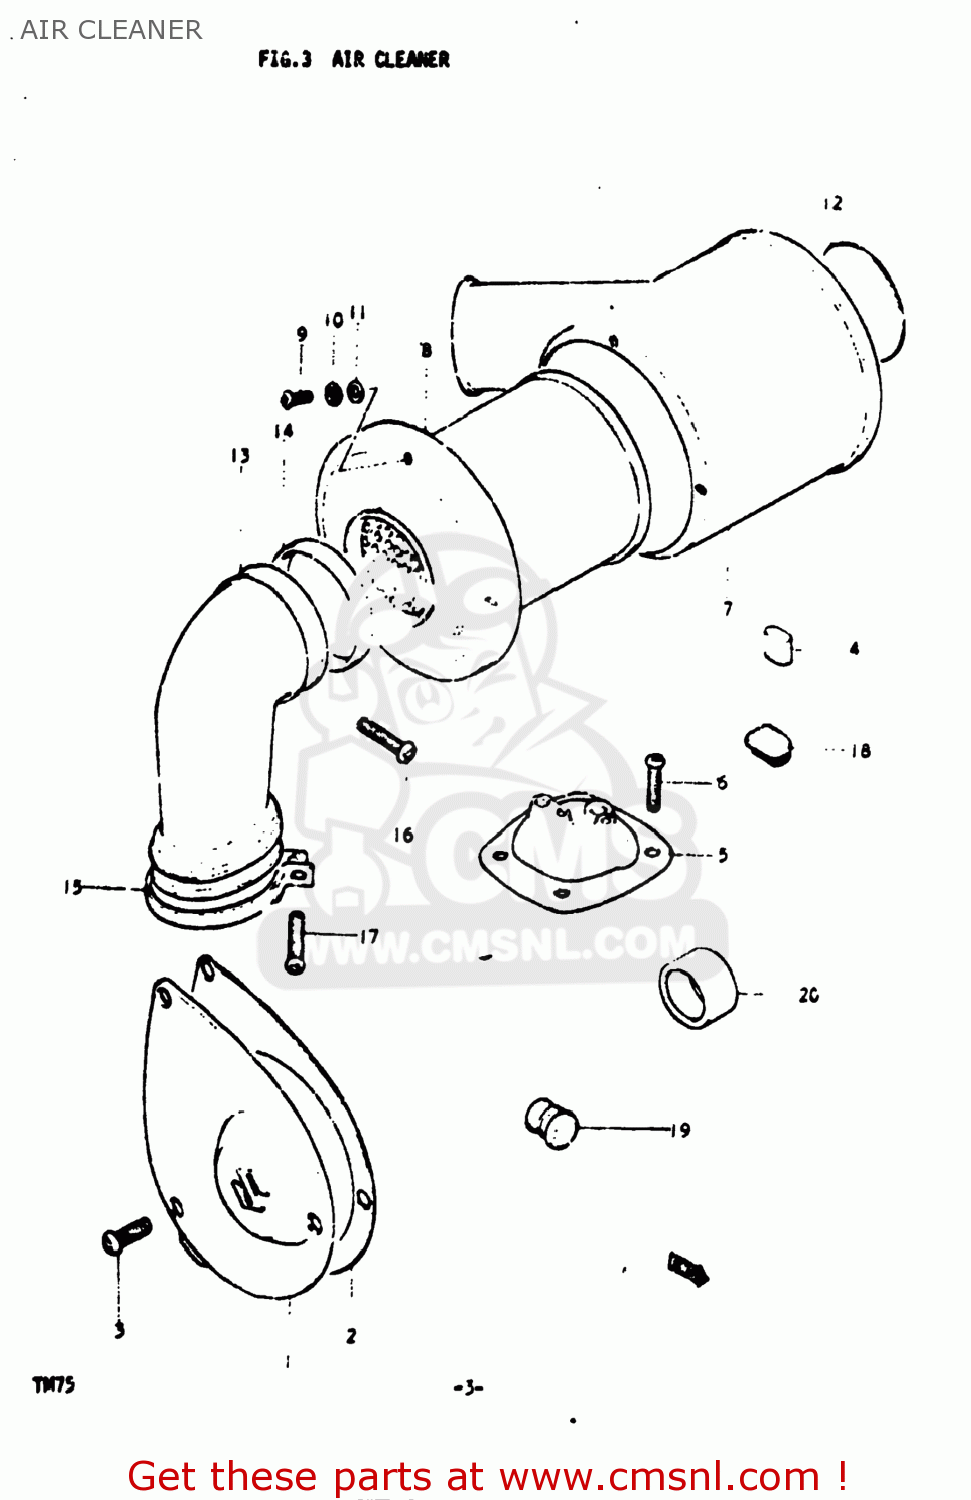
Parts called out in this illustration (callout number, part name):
1	CAP,CARBURETOR INSPECTION
2	GASKET,CARBURETOR INSPECTION (MCA)
3	SCREW
4	CUSHION
5	COVER,CARBURETOR TOP
6	SCREW
7	CLEANER ASSEMBLY,AIR
8	FILTER ASSY
9	SCREW
10	LOCK WASHER
11	WASHER
12	EMBLEM
13	TUBE,AIR CLEANER OUTLET
14	CLAMP
15	CLAMP
16	SCREW
17	SCREW TAPP.
18	CAP
19	Plug
20	GASKET,CARBURETOR INSULATOR (NAS)
